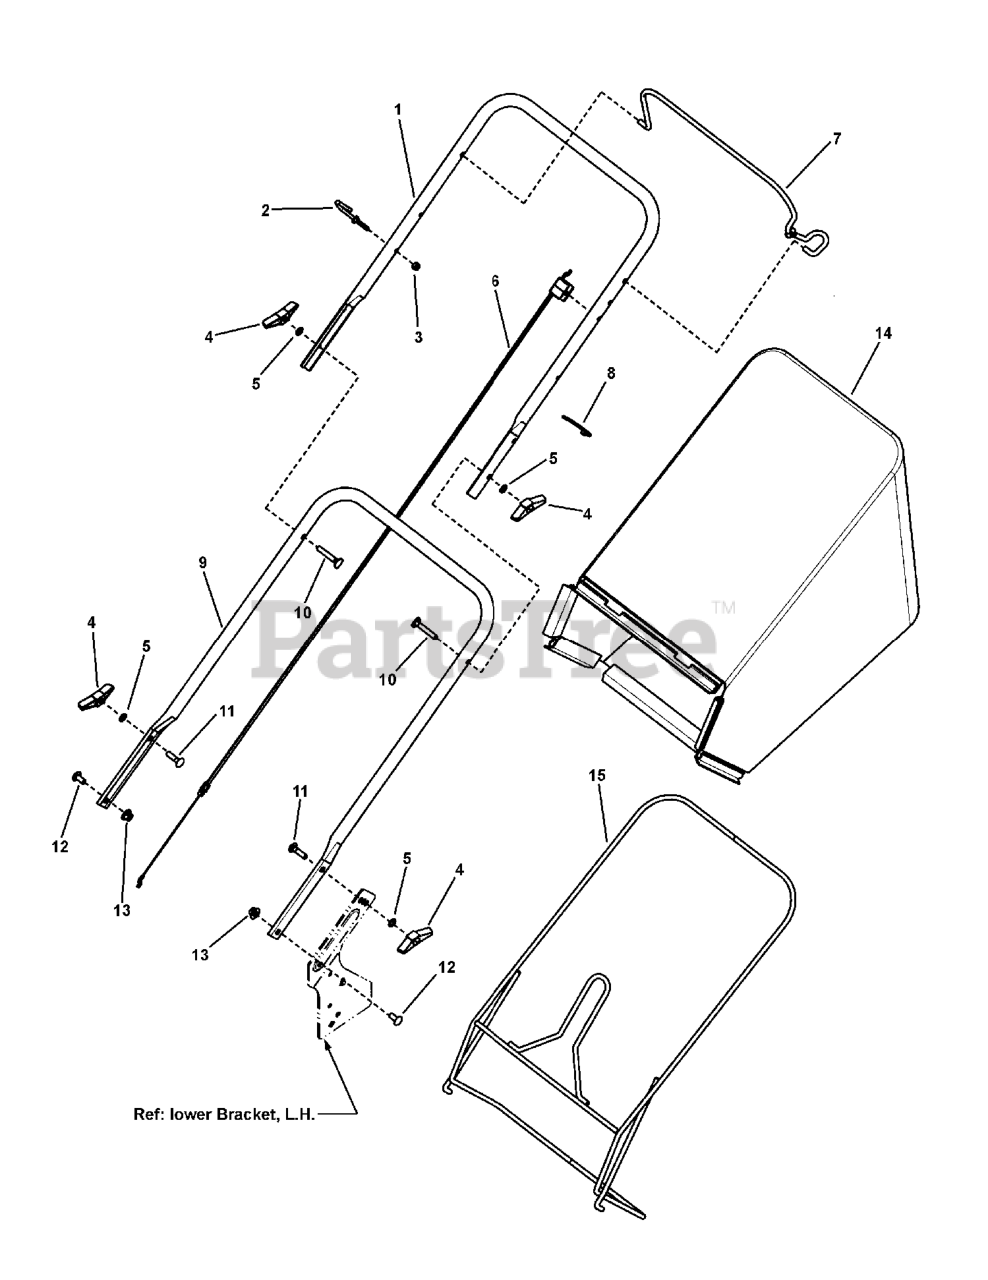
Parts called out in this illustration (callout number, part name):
1	UPPER HANDLE, Propelled
2	GUIDE, Rope (1/4-20 thread)
3	NUT, 1/4-20 Nyloc
4	KNOB, Wing, 5/16-18
5	WASHER, 5/16" Internal Tooth Lock
6	CABLE, Bail, 22" WBM, (41.50" overall length)
6	CABLE, Zone Control (48.60" overall length)
7	BAIL, OPC Push
8	WIRE TIE, 11 Inch Std Black Nylon
9	HANDLE, Lower
10	BOLT, 5/16-18 x 2" Curved Head Square Neck GR 2
11	BOLT, 5/16-18 x 1" Square Neck Carriage
12	BOLT 5/16-18 x 3/4" Round Head Short Square Neck
13	NUT, 5/16-18 Large Flange Center Lock
14	GRASS BAG, 22" Rear Discharge
15	WELDMENT, Frame, Grass Bag, 22" Walk-Behind
